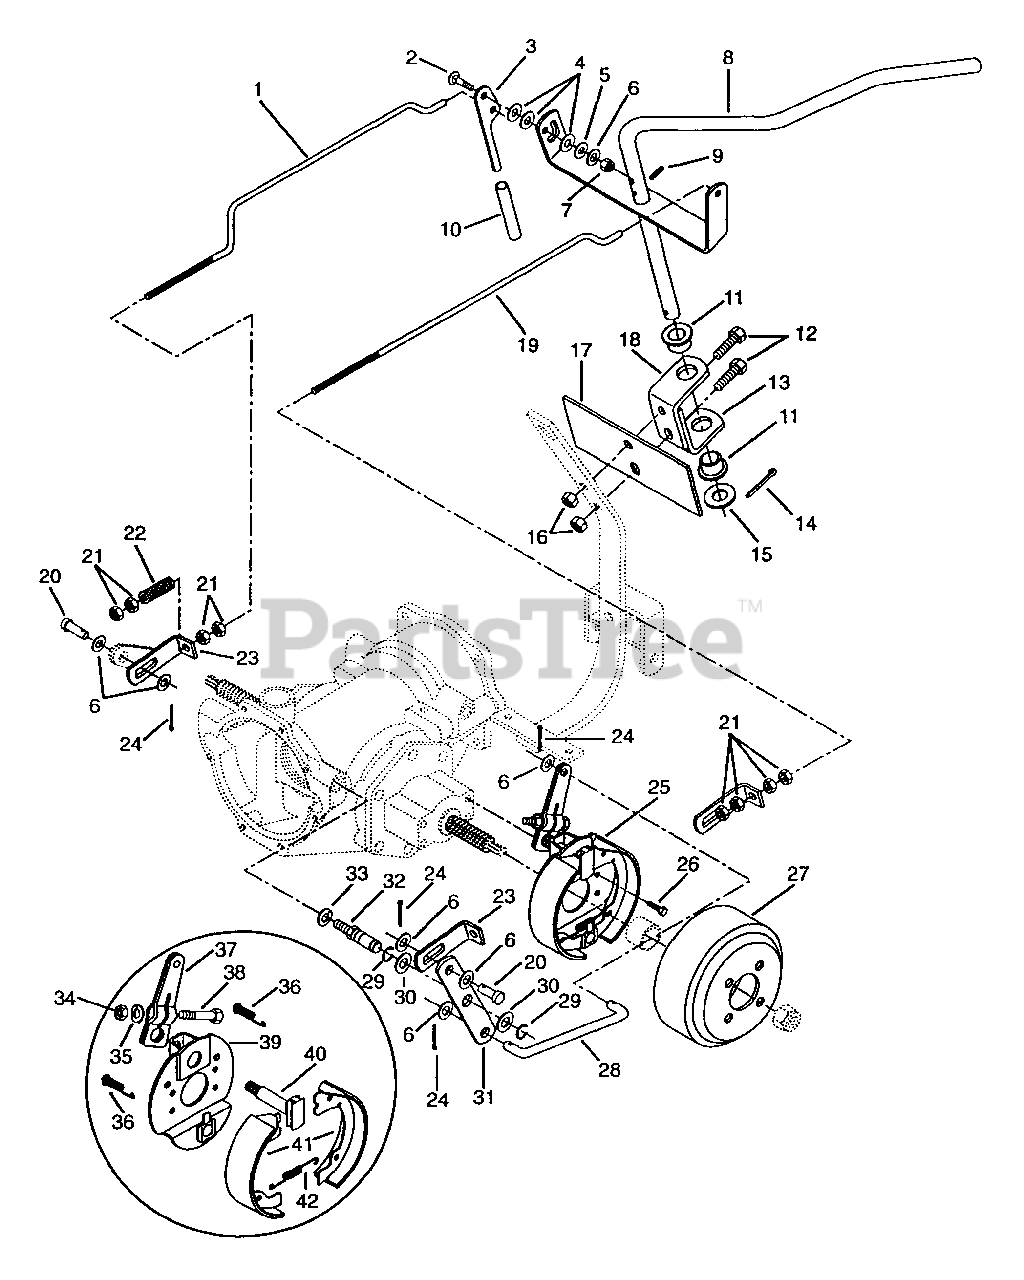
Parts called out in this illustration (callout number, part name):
1	Rod, Brake
2	Bolt-Round Head Square Neck .38-16 x 1.50
3	Handle, Parking Brake
4	Washer-Flat-Nylon .375 x .75 x .060
5	Washer-Rubber .375 x .75 x .125
6	Washer-Flat-Steel .406 x .812 x .065
7	Nut-Locking-Nylon .375-16 Grade 2
8	Weldment, Brake Handle
9	Pin-Roll .313 x 2.00
10	Grip, Brake Handle
11	Bushing-Flange 1.082 x 1.385 x.870 x 1.750
12	Bolt-Hex .50-13 x 2.00 Grade 5
13	Bracket, Brake Handle
14	Pin-Cotter .188 x 1.50
15	Washer-Flat-Steel 1.120 x 1.500 x .092
16	Nut-Locking-Nylon .50-13 Grade 5
17	Plate, Instruction
18	Bracket, Brake Handle
19	Rod, Brake Left Hand
20	Pin, Clevis 3/8 x .750
21	Nut-Jam .375-16
22	Spring-Compression .105 x .61 x 2.50
23	Bracket, Adjustment
24	Pin-Cotter .09 x .75
25	Brake,7 x 1-3/4 Mechanical
26	Bolt-Hex .380-16 x .875
27	Drum, 7 x 1-3/4
28	Rod, Brake Link
29	Ring-Retaining-External .625 x .042
30	Washer-Flat-Steel .656 x 1.312 x .095
31	Plate, Pivot
32	Stud, Pivot
33	Washer-Lock .50 Reg.
34	Nut-Hex .312-24 Grade 2
35	Washer-Lock .313 x .078
36	Spring, Shoe Ret Box
37	Arm, Cam Lever
38	Bolt-Hex .31-24 x 1.75
39	Plate, Back
40	Cam, Brake
41	Kit, Brake Shoe
42	Spring, Shoe Return
